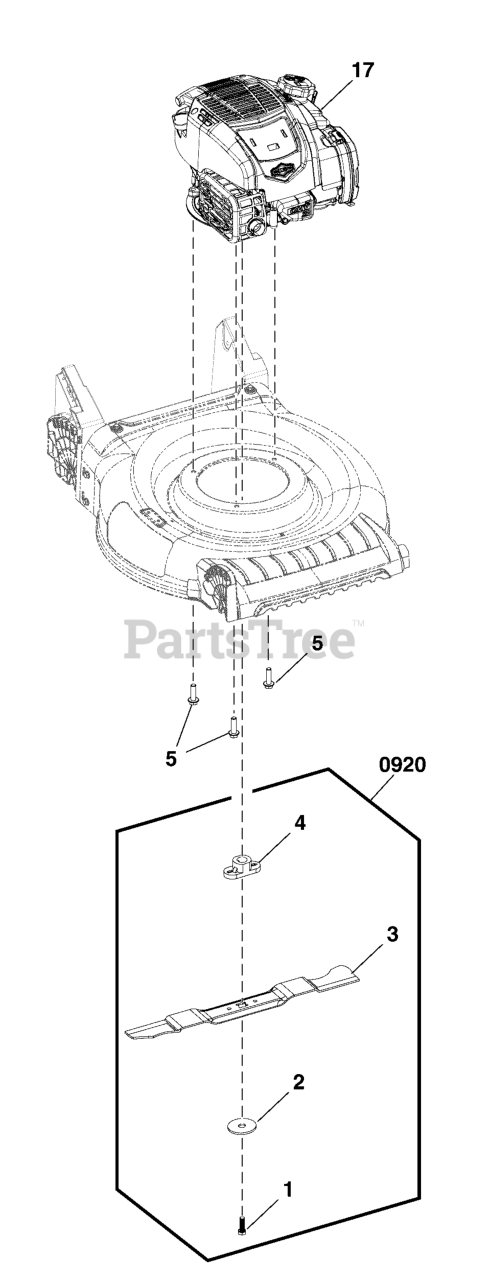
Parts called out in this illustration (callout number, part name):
1	BOLT, Blade
2	WASHER
3	BLADE, Mower
4	ADAPTER, Blade
5	BOLT
17	ENGINE
0920	KIT, Blade
